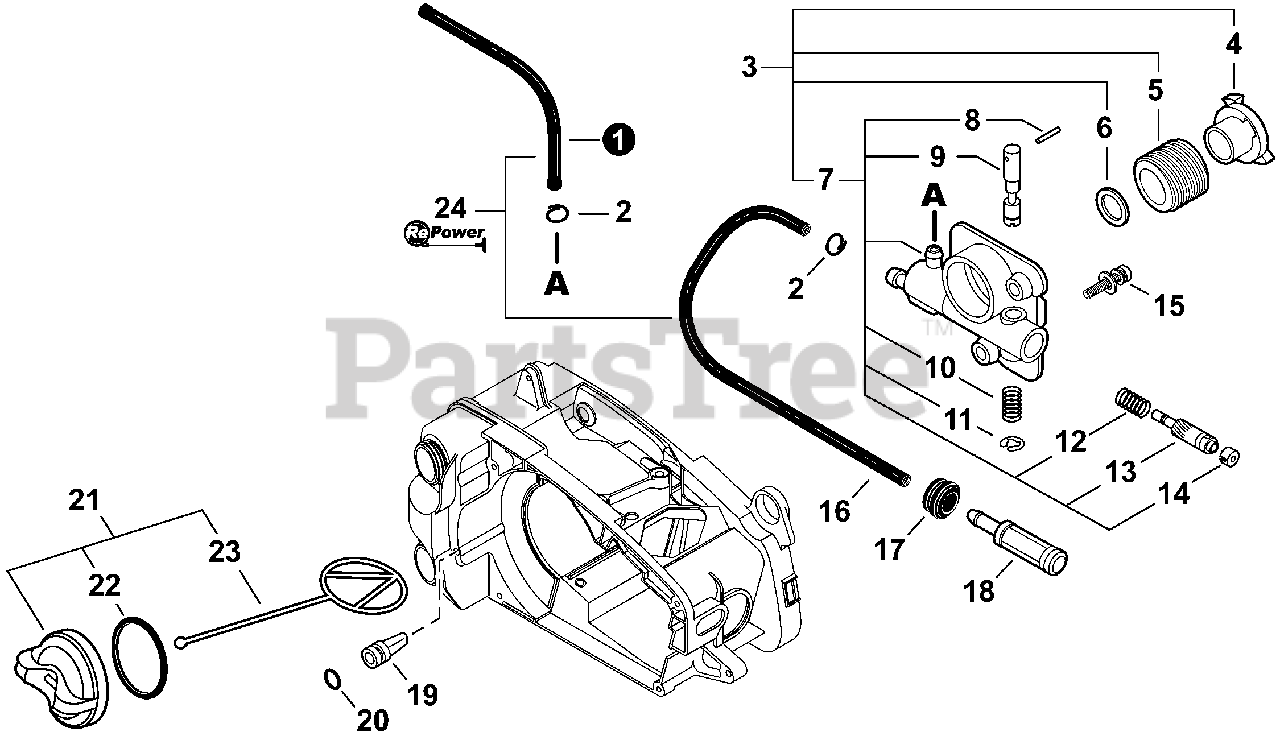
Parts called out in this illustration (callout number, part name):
1	PIPE 3×6×90mm
2	CLIP Ø6.5MM
3	AUTO-OILER ASSY
4	COLLAR 10
5	GEAR, WORM
6	WASHER 10.5×17.4×1.8
7	AUTO-OILER
8	PIN, SPRING
9	ADJUSTER, OILER
13	PLUNGER ASSY
14	CAP, OIL PUMP
15	SCREW 4×12
16	PIPE, OIL 3×6×160
17	GROMMET
18	FILTER, OIL
19	VENT ASSY
20	O-RING S-4
21	CAP ASSY, BLACK
22	O-RING 18
23	CONNECTOR, CAP L= 60mm
24	PIPE, BULK - REPOWER 3×6mm BLACK
